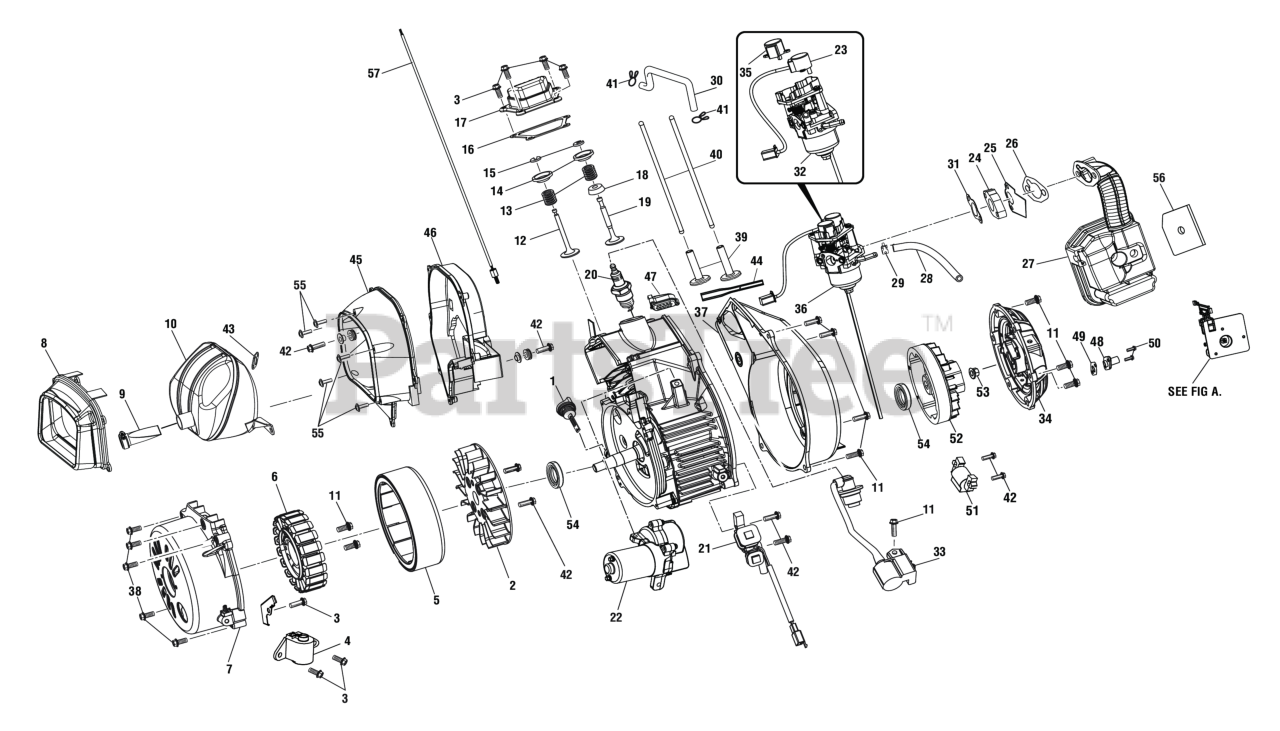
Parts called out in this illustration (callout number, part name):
1	Oil Dipstick
3	Bolt (M6 x 12 mm)
4	Low Oil Sensor
7	Alternator Cover
8	Muffler Heat Shield
9	Spark Screen
11	Bolt (M6 x 16 mm)
12	Exhaust Valve
13	Valve Spring
15	Valve Lock Clamp
16	Gasket (Over Head Cover)
17	Over Head Cover
18	Inlet Valve Spring Seat
19	Inlet Valve
20	Spark Plug
21	RPM Sensor
22	18V Electric Starter Motor
23	Stepper Motor for Auto-Choke
24	Thermal Insulation Seat (Carburator)
25	Paper Gasket
26	Air Box Gasket
27	Air Filter Assembly
28	Fuel Hose (6 mm)
29	Fuel Line Clamp (7/16 in., BM903611)
30	Breather Pipe
31	Gasket (Muffler)
32	Carburetor
33	Ignition Coil
34	Engine Recoil
35	Stepper Motor
36	Carburetor Assembly (Inc. Key Nos. 23, 32 and 35)
37	Engine Cover
38	Bolt (M6 x 30 mm)
39	Lifter Valve
40	Pushing Rod
42	Bolt (M6 x 20 mm)
43	Gasket (Connection Block)
44	Breather Hose
45	Muffler Cover 1
46	Muffler Cover 2
47	Fill Valve Assembly
48	Ring Flange
49	Oil Ring
50	Bolt (M5 x 12 mm)
51	Magneto Ignition
52	Flywheel
53	Flywheel Nut
54	Oil Seal
56	Air Filter
57	Head Temperature Sensor
